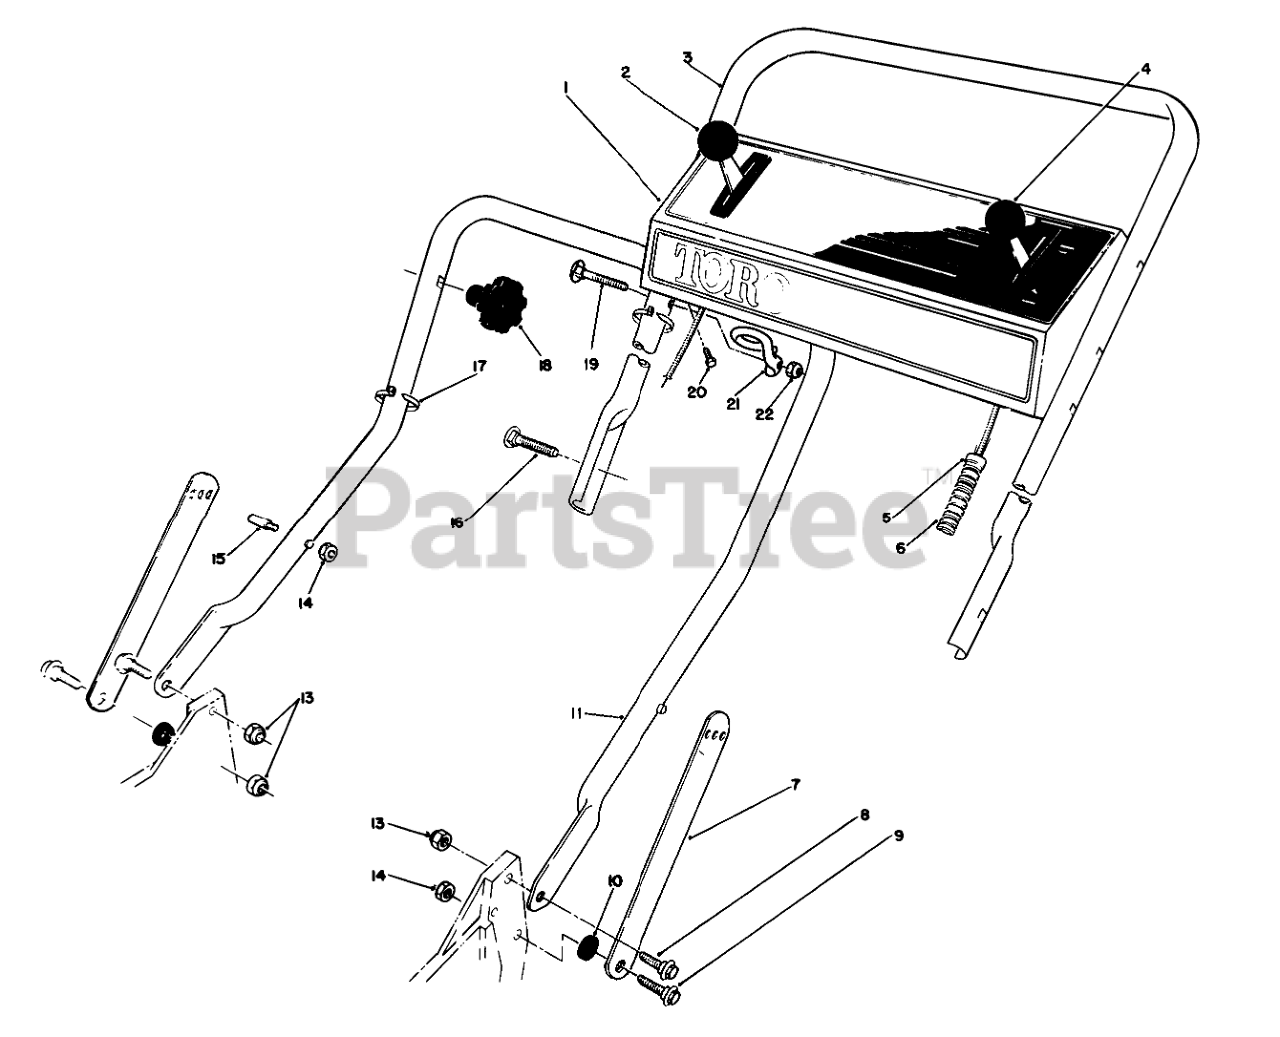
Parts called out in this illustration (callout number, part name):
1	Panel-Control
2	GROUND SPEED CONTROL
3	UPPER HANDLE
4	THROTTLE CONTROL
5	FITTING-RING
6	CONTROL CABLE COVER
7	Handle Latch
8	SCREW-SHOULDER
9	SCREW-SHOULDER
10	SPACER
11	LOWER HANDLE ASM
13	NUT-LOCK, NI
14	NUT-LOCK, NI
15	HANDLE PIN
16	5/16-18 X 2 HNDLE SCREW
17	TIE-CABLE
19	HANDLE SCREW
20	SCREW-HWHTF
21	Guide
22	NUT-LOCK, NI
